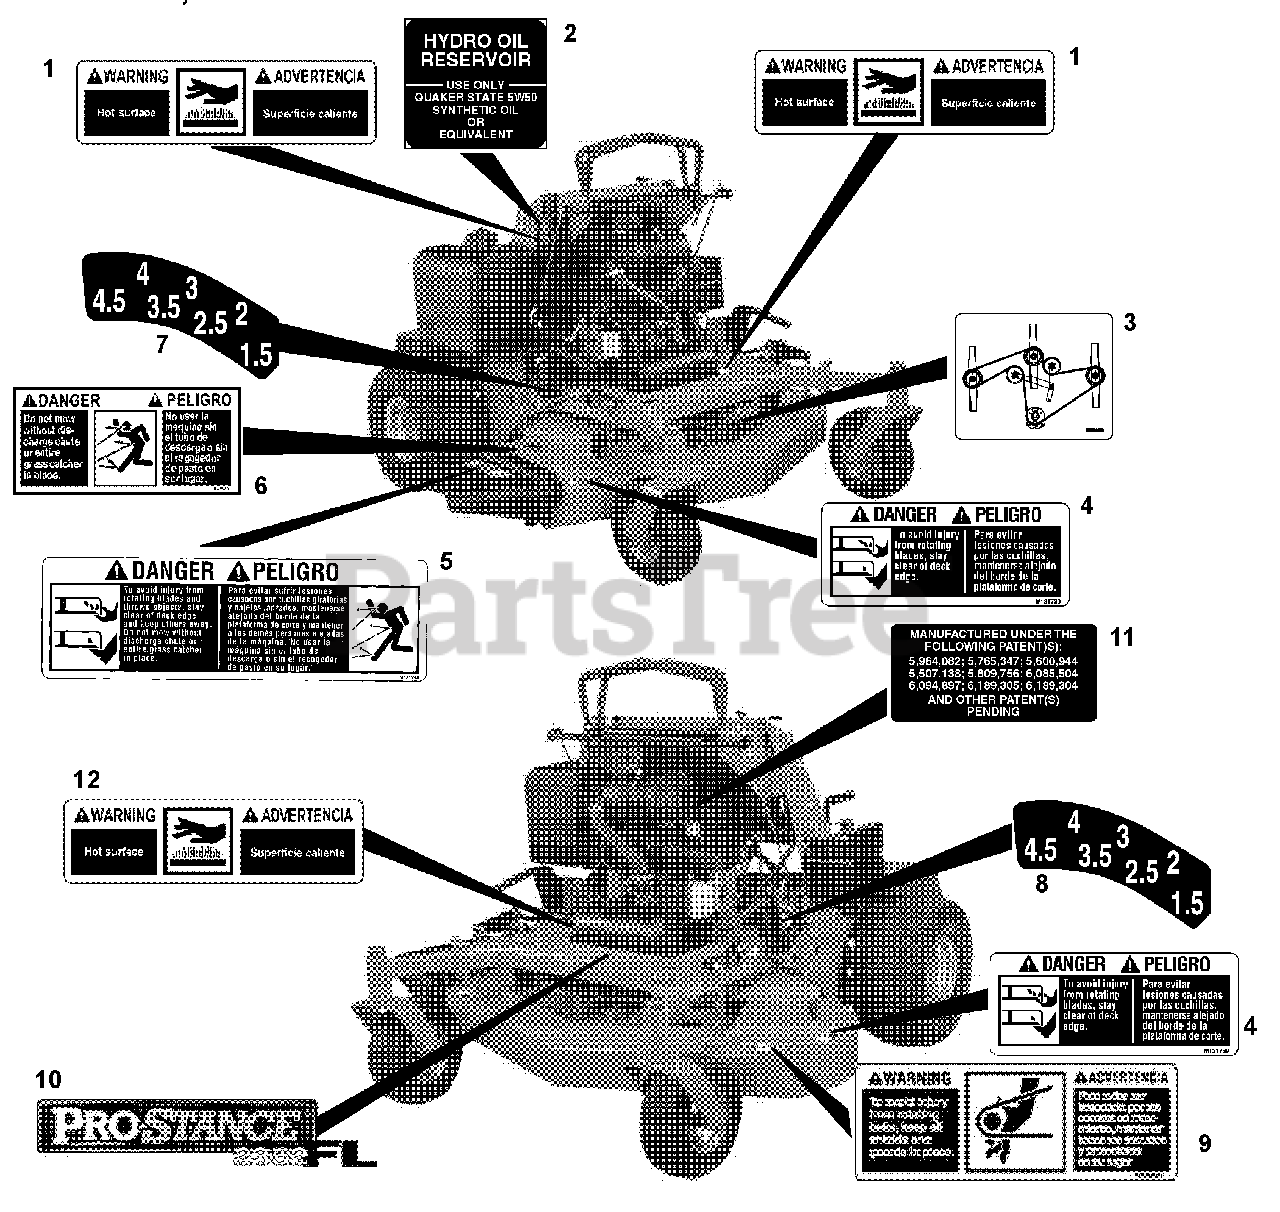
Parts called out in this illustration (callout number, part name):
1	Decal, Warning, Hot Surface (994100)
2	Decal, Hydro Oil Reservoir
3	Decal, Belt Path
4	Decal, Danger - Blade Contact
5	Decal, Danger - Thrown Objects
6	Decal, Danger - Rotating Blades
7	Decal, Cut Height RH
8	Decal, Cut Height, LH
9	Decal, Danger - Rotating Belts
10	Decal, Pro-Stance 1948FL (994100)
11	Decal, Patent
12	Decal, Warning, Hot Surface (994103)
